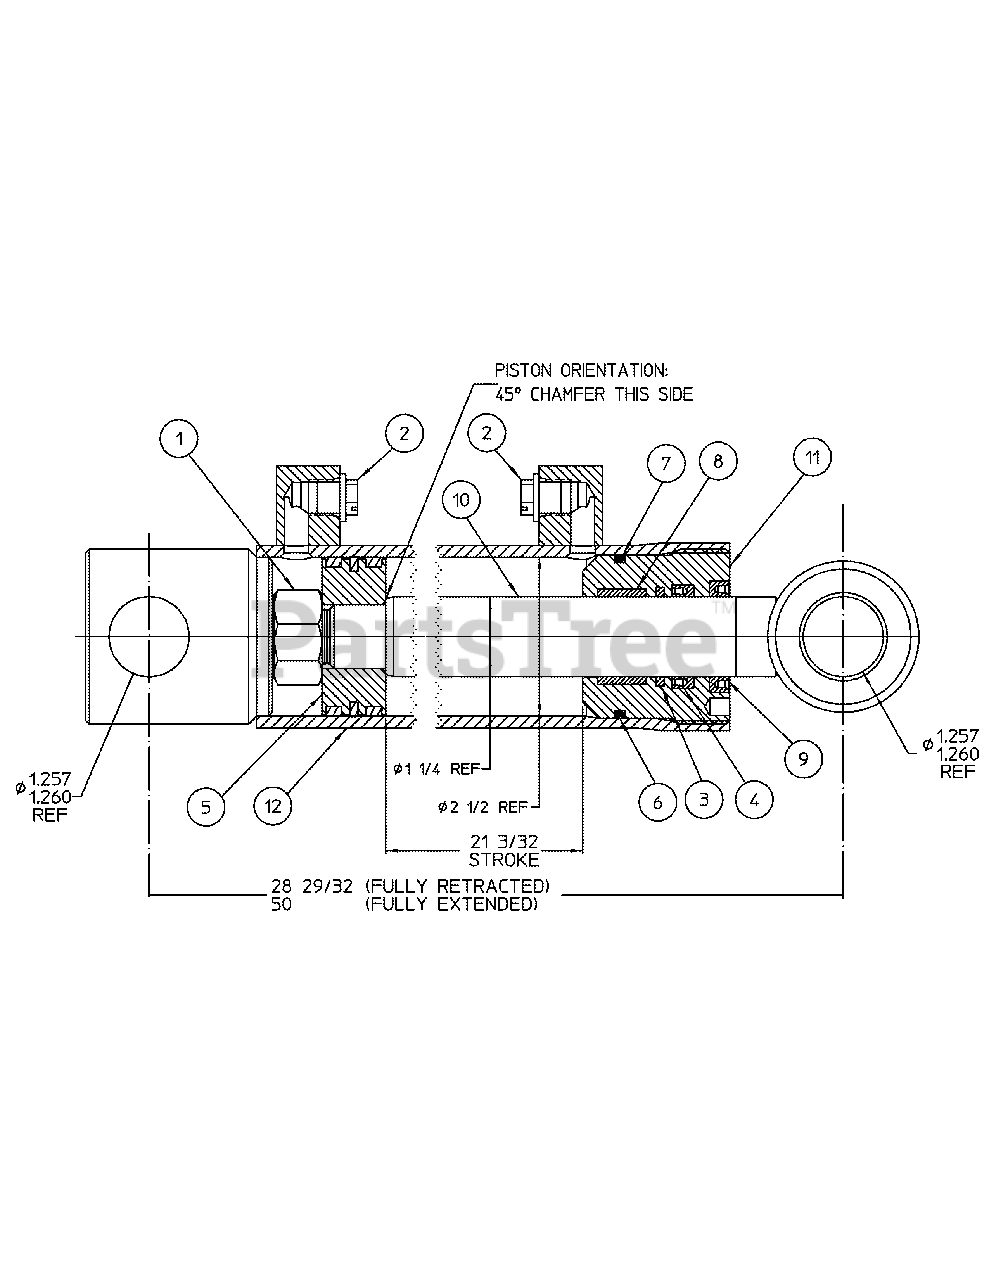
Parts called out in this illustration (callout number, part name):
1	Nut, 7/8 NF Lock
3	Step Seal
4	U-Cup Seal
5	Piston Assembly
6	O-Ring, 2-9/16" x 2-3/8 ID
7	Back-Up Ring
8	Wear Ring
9	Rod Wiper
10	Piston Rod Weldment
11	Gland with O-Rings, Back-Up, etc.
12	Cylinder Tube Weldment
